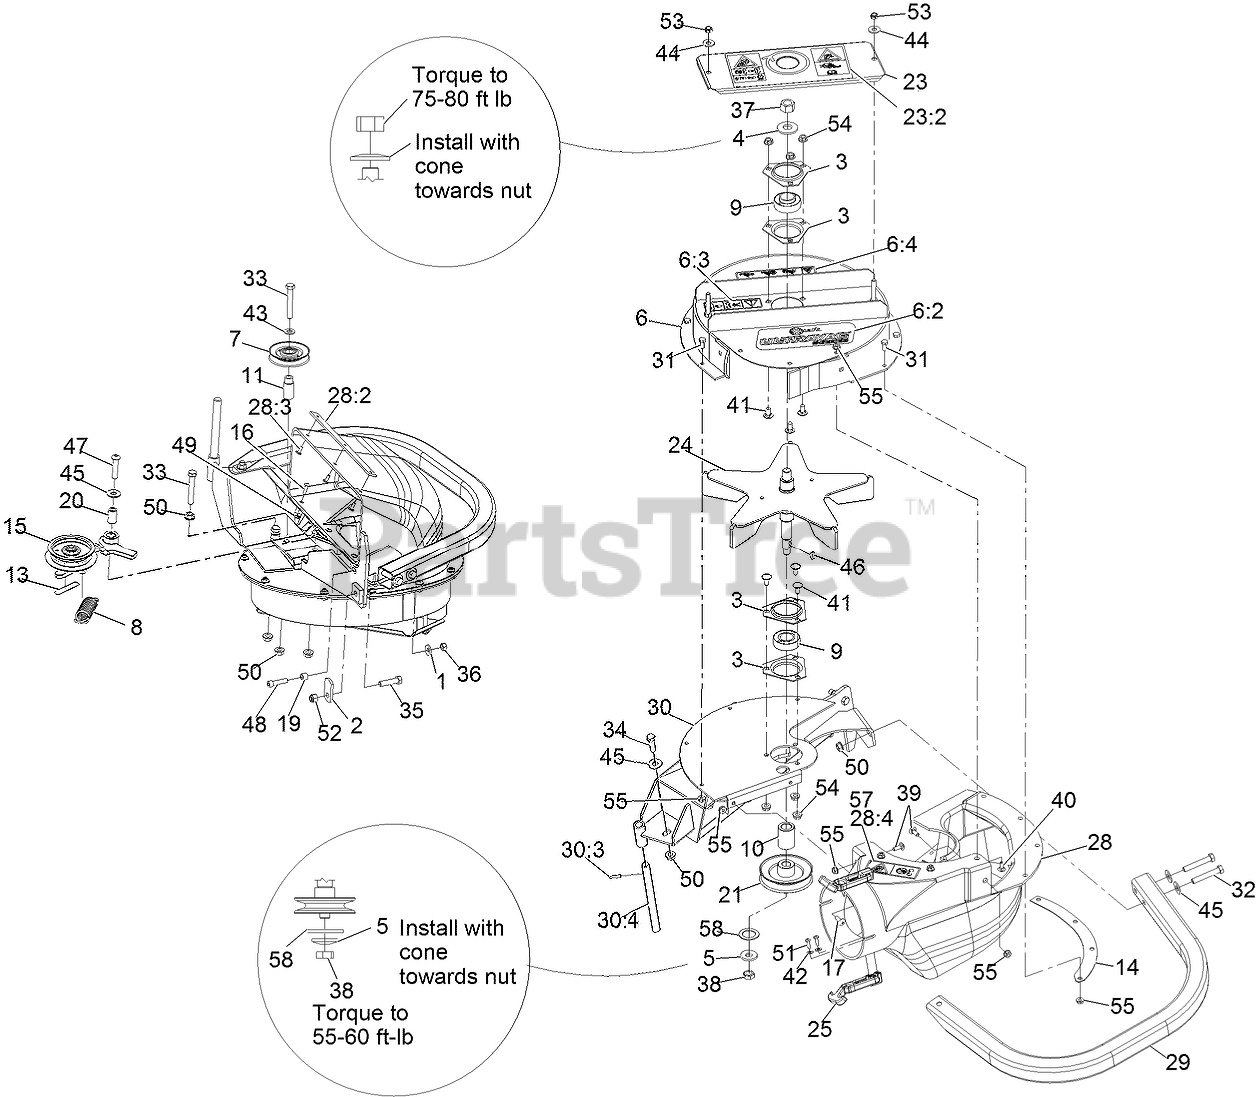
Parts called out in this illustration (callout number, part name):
1	WASHER-SPRING
2	LATCH-CATCHER, GRASS
3	HOUSING-FLANGE
4	WASHER-SPRING
5	WASHER-SPRING
6	ASM-UPPER HOUSING SMALL
6:2	Decal-Ultravac S-Series
6:3	DECAL-COVER, MISSING
6:4	DECAL-WARNING WEIGHT
7	IDLER-INSIDE
8	SPRING-IDLER
9	BEARING
13	DECAL-WARNING
14	PLATE-BACKING, BLOWER
15	ASM, Idler
16	SCREW-HEAD, TRUSS
19	BUSHING, LOCATOR
20	BUSHING-PIVOT, IDLER
21	SHEAVE-BLOWER
23	ASM, BEARING COVER
23:2	Decal-Warning Blower
24	IMPELLER
25	LATCH-RUBBER
28	ASM,BLOWER CHUTE LHP
28:2	PLATE-REINFORCEMENT
28:3	RIVET-BLIND
28:4	Decal-Blower-Impeller Hazard
30	WELD, FRAME SM BLOWER
30:3	PIN-ROLL
30:4	SHAFT-CATCHER, GRASS
31	SCREW-HH
32	SCREW-HH
33	SCREW-HH
34	SCREW-HH
35	SCREW-HH
36	NUT-HEX
37	NUT-HEX
38	NUT-JAM
39	BOLT-CARR
40	SCREW-CARR
41	SCREW-CARR
42	WASHER-FLAT
43	WASHER-FLAT
44	WASHER-FLAT
45	WASHER-FLAT
46	KEY-WOODRUFF
47	SCREW-HSBH
48	SCREW-HSH
50	NUT-HHF, WHIZ
51	SCREW-PPH
52	NUT-LOCK, NI
53	NUT-LOCK, NI
57	Decal-Blower-Impeller Hazard
58	WASHER-SPACER
